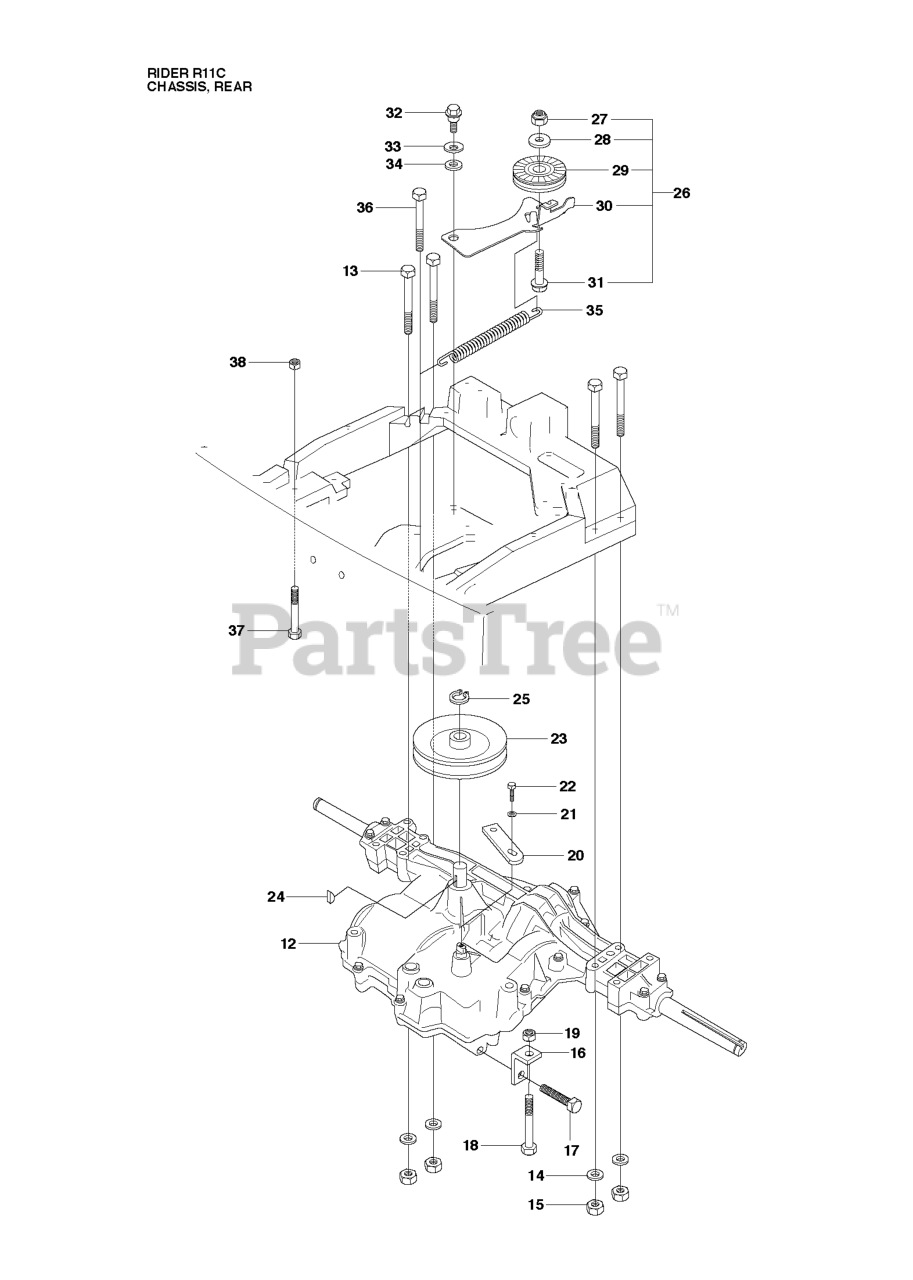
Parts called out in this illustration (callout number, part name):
14	WASHER BRB 8.4X17
15	NUT
16	Wire Bracket
18	SCREW
19	NUT
21	WASHER
25	Retaining Ring Sga 16
27	LOCKNUT M8
31	SCREW
33	SPRINGWASHER
34	WASHER - M12
37	SCREW
38	NUT
